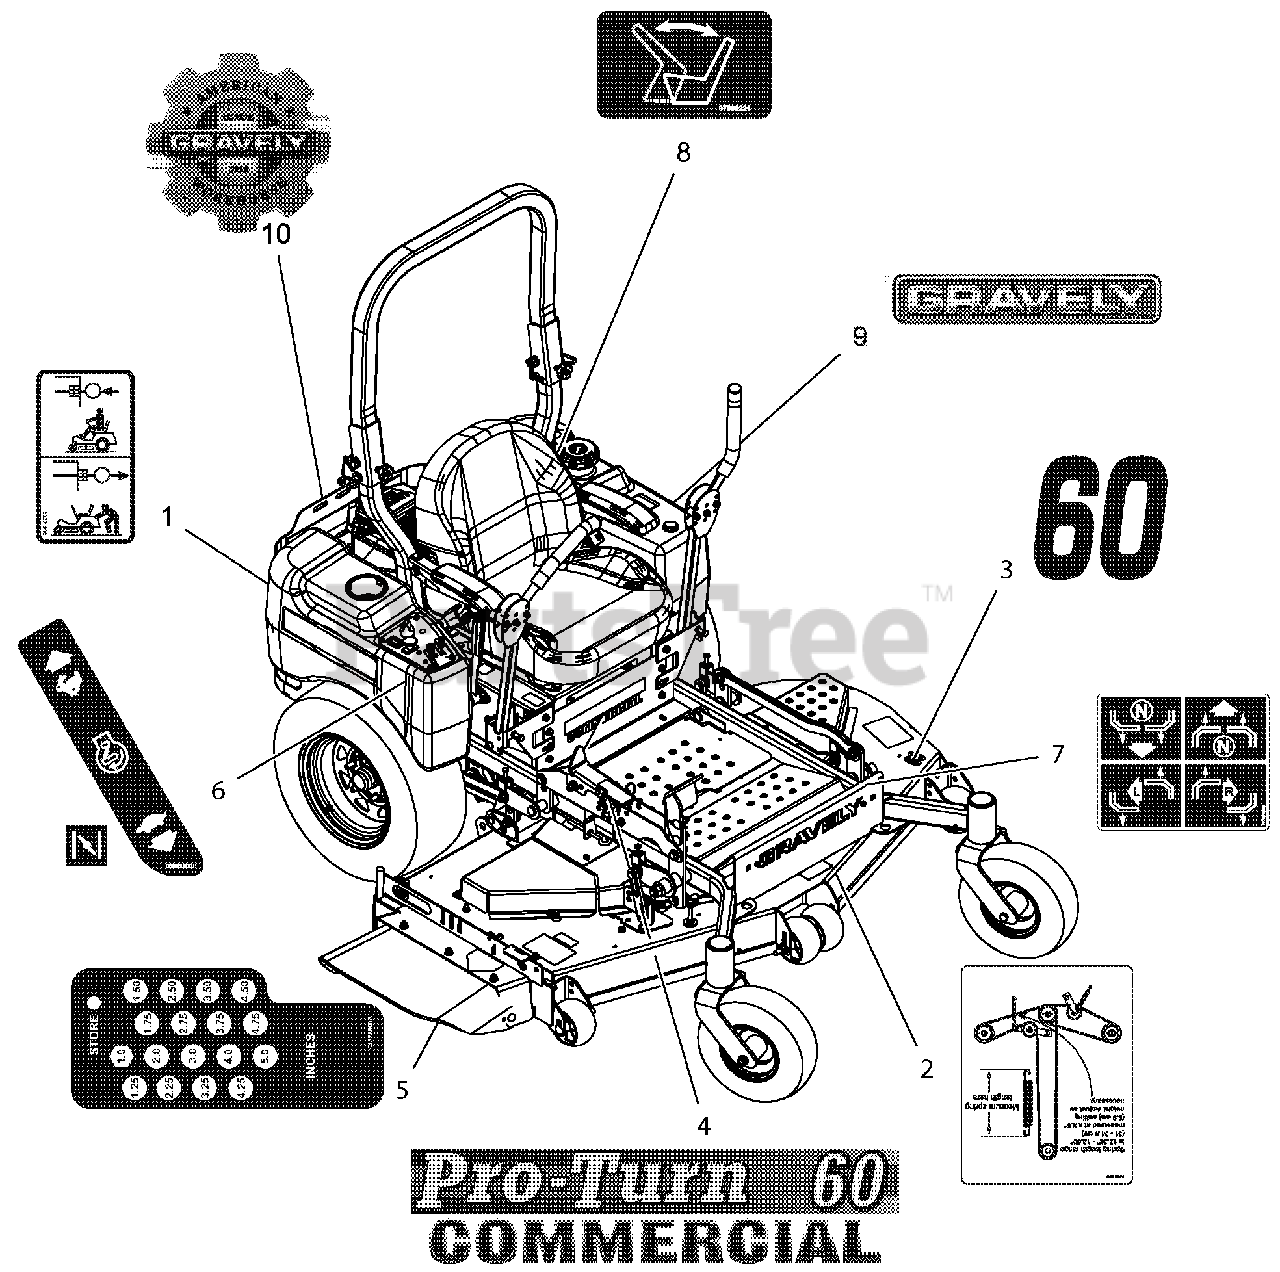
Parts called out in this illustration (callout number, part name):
1	DECAL, TRANSMISSION DISCONNECT
2	DECAL, BELT ROUTING
3	DECAL, 60"
4	DECAL, HEIGHT OF CUT
5	DECAL, 60" PRO-TURN
6	DECAL, SPEED CONTROL
7	DECAL, INSTRUCTIONAL - STEERING
8	DECAL, SEAT RELEASE
9	DECAL, FUEL TANK-GRAVELY
10	DECAL, GRAVELY HERITAGE-LARGE
